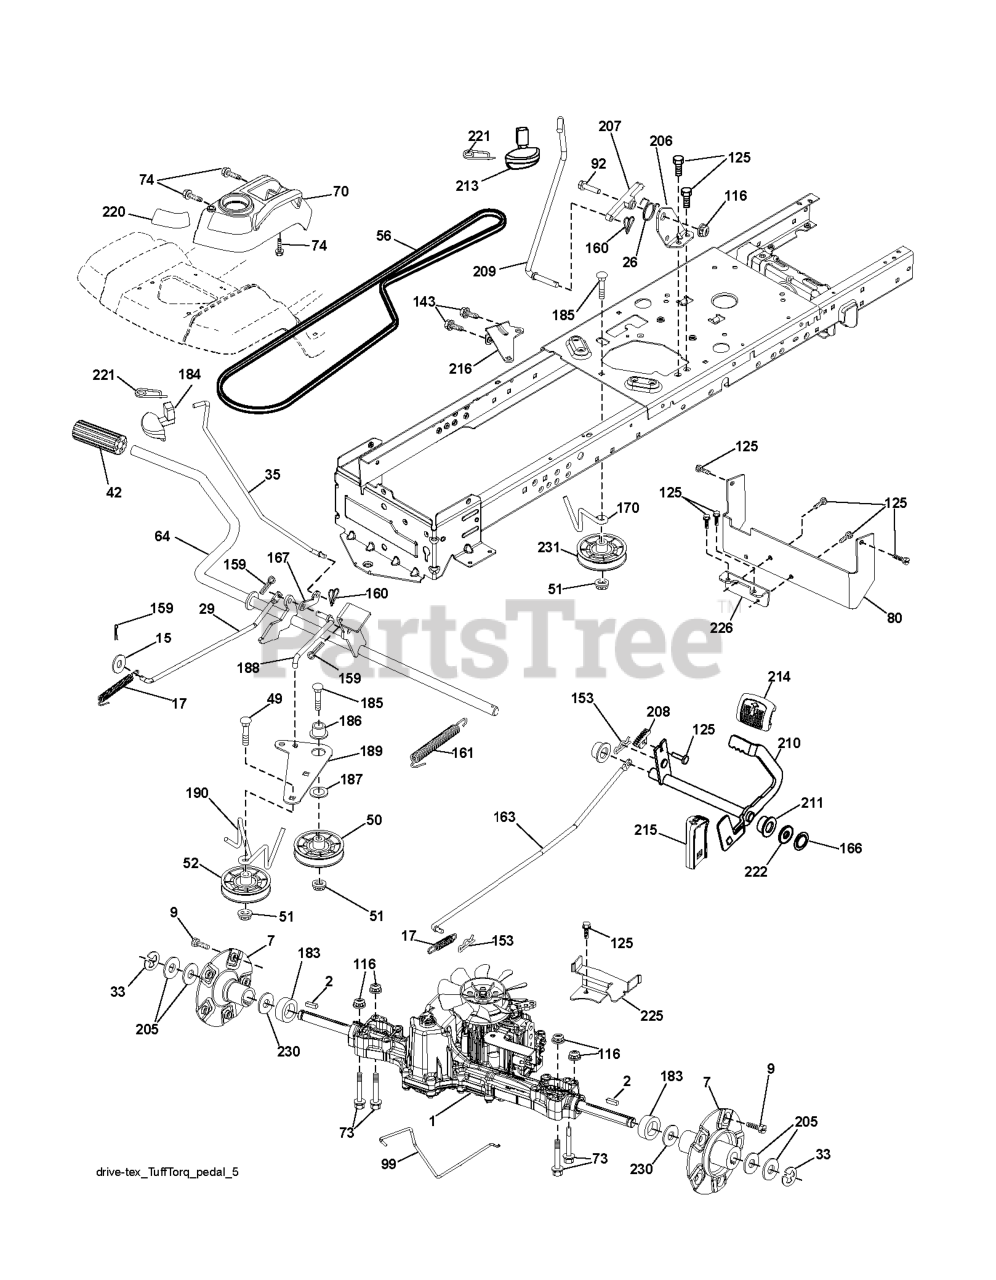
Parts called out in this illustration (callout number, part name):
2	KEY.SQUARE.187X2.500
7	HUB.ASM.WHEEL.REAR.22"
15	WASHER
17	SPRING.BRAKE.K46.GREEN
26	SPRING.RETURN.CRUISE
29	ROD.BRAKE.K46
35	ROD.BRAKE.PARKING.GT.H
42	PEDAL COVER T
50	IDLER.FLAT.910.OFFSET
51	NUT LOCK FLG 3/8-16 UNC
52	IDLER.V-GROOVE.910.OFFSET
56	V-BELT.MOWER.92.40.42/K46
64	SHAFT.ASM.PEDAL.BRK.CNTR
70	RP CONSOLE.ASM.PCH.W/TB
73	BOLT HEX 5/16-18 GR 5
74	SCREW.HI-LO.CONSOLE
80	STRAP TORQUE
92	BOLT
99	ROD.SPRING.BYPASS.K46.LT.Z
116	NUT LOCK HEX FLANGE 5/16-18
125	SCREW
143	Screw 5/16-18 x 1/2 Hex, Self Tapping 5/16-18 x 1/2
153	RETAINER M
159	COTTER PIN
160	RETAINER CLIP
161	SPRING, RETURN LT
163	ROD.CONTROL.PEDAL.K46
166	NUT.PUSH.625.2006
167	LATCH.BRAKE.SPRING
170	KEEPER.V-IDLER.CENTER.
183	SPACER.SPLIT.800X.350
184	HANDLE.PARKG.BRK.HUSQ X667
186	SPACER.RETAINER
187	WASHER 12/32X2X10GA
188	RP.LINK.CLUTCH.GROUND.DRIVE
189	BELLCRANK.GROUND.DRIVE.TEX.
190	KEEPER.BELLCRANK.DRIVE
196	SCREW 3/8-16X1
197	BRKT.ANIT-ROTATION.CLUTCH
206	BRKT.MOUNT.LATCH.CRUIS
207	LATCH.CONTROL.CRUISE
208	GEAR.SECTOR.CONTROL.CR
209	ROD.CONTROL.CRUISE.GT.
210	ROCKER.ASM.PEDAL.CONTR
211	BEARING.NYLON
213	KNOB.CONTROL.CRUSIE.HU
214	PEDAL.FORWARD.TEX.GT.4
215	PEDAL.REVERSE.TEX.GT.4
216	BRACKET.PULLEY.IDLER.W/TEX
220	REFLECTOR.RH.TEX GT
221	RETAINER.SPRING.CLIP.H
222	WASHER 21/32 X 1-1/4 X 10 GA.
225	KEEPER.BELT.TRANSAXLE.K46
226	BRACKET.MOUNT.TORQUE.K46.TLT
230	WASHER.HARDENED
231	IDLER.V-GROOVE.1.688.OFFSET
